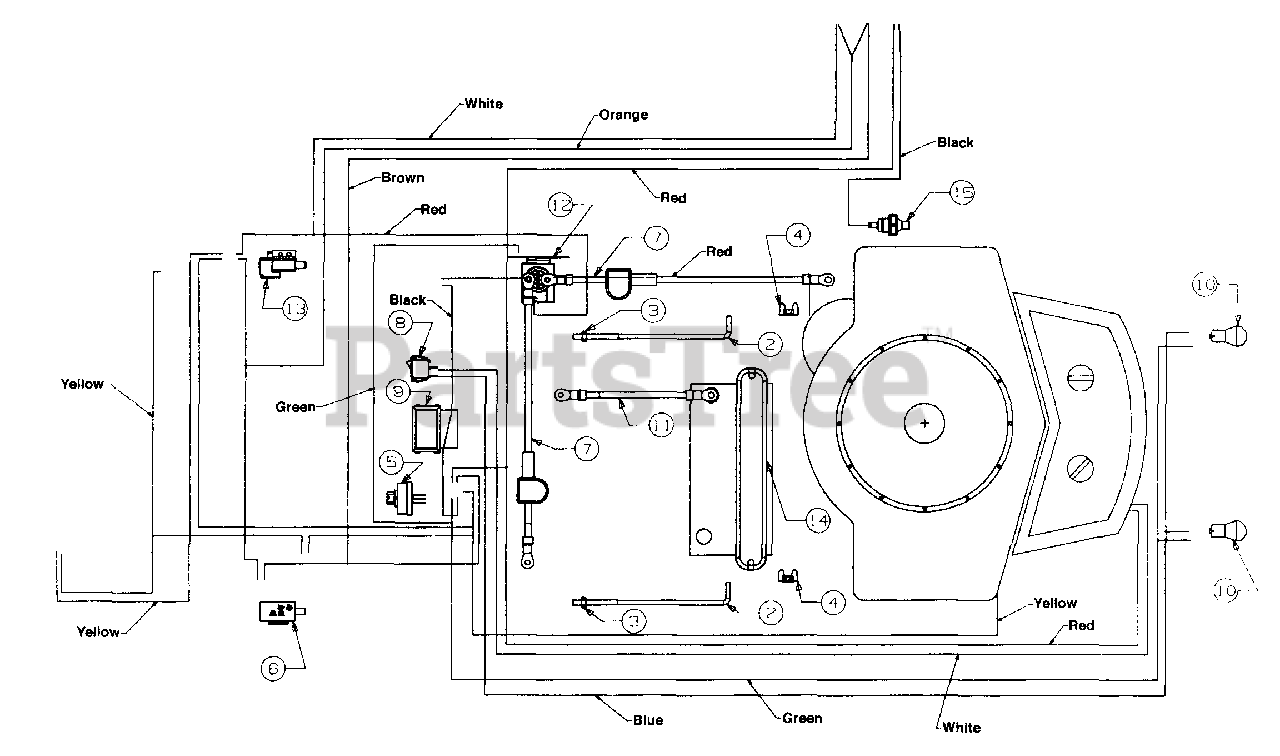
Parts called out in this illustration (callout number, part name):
2	Battery Hold Down Rod
3	Hex L-Nut 1/4-20 Thd.
4	Wing Nut 1/4-20 Thd,
5	Ignition Switch
6	Safety Switch (PTO)
7	Wire w/Boot 14" Lg.
8	Light Switch
9	Ammeter
10	Bulb
11	Wire 7.5" Lg
12	Solenoid
13	Safety Switch (Clutch)
14	Battery Cover
15	Oil Pressure Switch
